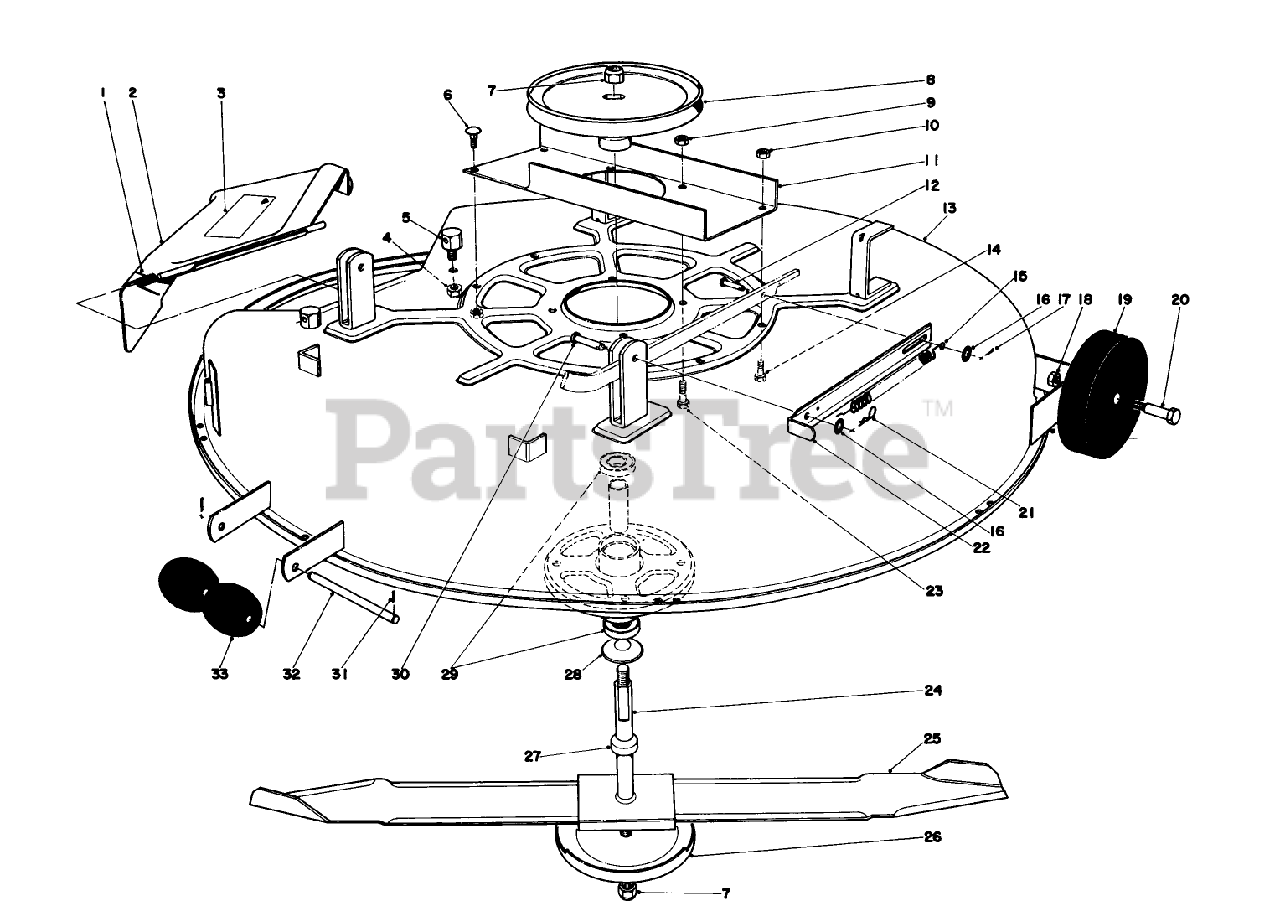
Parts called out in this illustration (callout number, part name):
1	SPRING
4	NUT-LOCK, SIDE
5	POST-PIVOT
6	SCREW-CARR
7	NUT-SPECIAL
9	NUT-LOCK, CONE
12	PIN-CLEVIS
14	SCREW-HH
16	WASHER-FLAT
17	PIN-COTTER
21	PIN-COTTER
23	SCREW-HH
28	DUST COVER
29	BEARING-BALL
30	PIN-CLEVIS
31	PIN-COTTER
33	ROLLER
